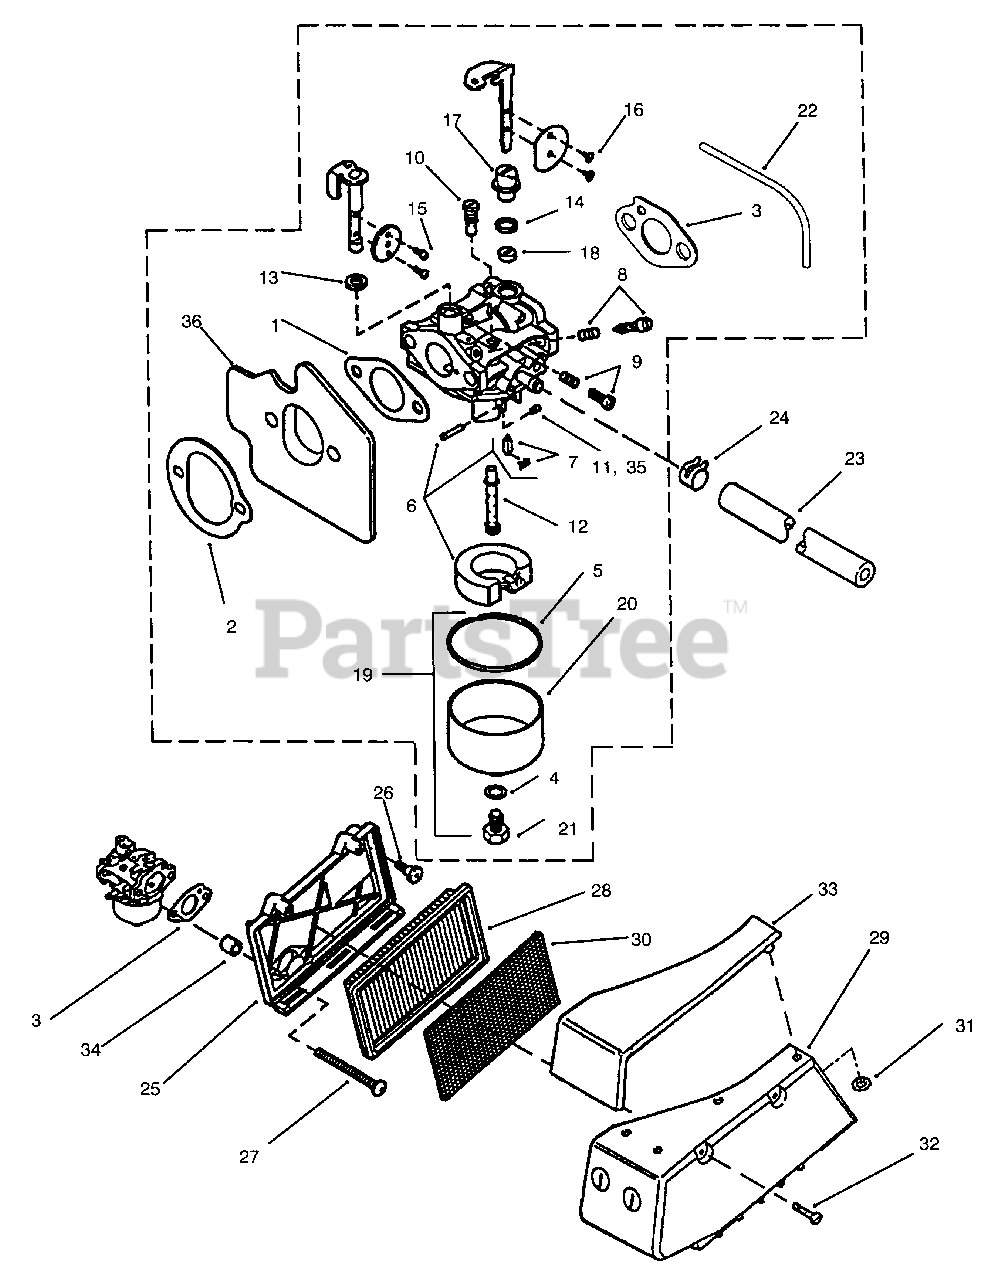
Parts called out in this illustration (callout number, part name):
1	Gasket-Carb. to Spacer
2	Gasket-Spacer to Engine
3	Gasket-Air Filter Base
4	Gasket-Bowl Retainer
5	Gasket-Fuel Bowl
6	Kit-Float & Needle (Incl. Ref. No. 7)
7	Needle and Clip
8	Kit-Idle Needle & Spring
9	Kit-Idle Speed
10	Pilot Jet
11	Main Jet
13	Seal-Throttle Shaft
14	Seal-Choke Shaft
15	Screw-Throttle Valve
16	Screw-Choke Valve
17	Pivot-Upper Choke Shaft
18	Pivot-Lower Choke Shaft
19	Kit-Bowl (Incl. Ref. No. 20-21)
20	Bowl-Fuel
21	Screw-Bowl Retainer
22	Hose-Carb Vent
23	Gas Line
24	Clamp-Hose
25	Base-Air Filter
27	Screw-Carb. to Engine
28	Filter-Air
29	Assembly-Cover, Air Filter (Incl. Ref..No. 30-33)
30	Pre-Filter
31	Pushnut
33	Cover-Air Box
35	Main Jet-High Altitude (Over 3500 feet)
36	Assy.-Spacer & Oil Nozzle
